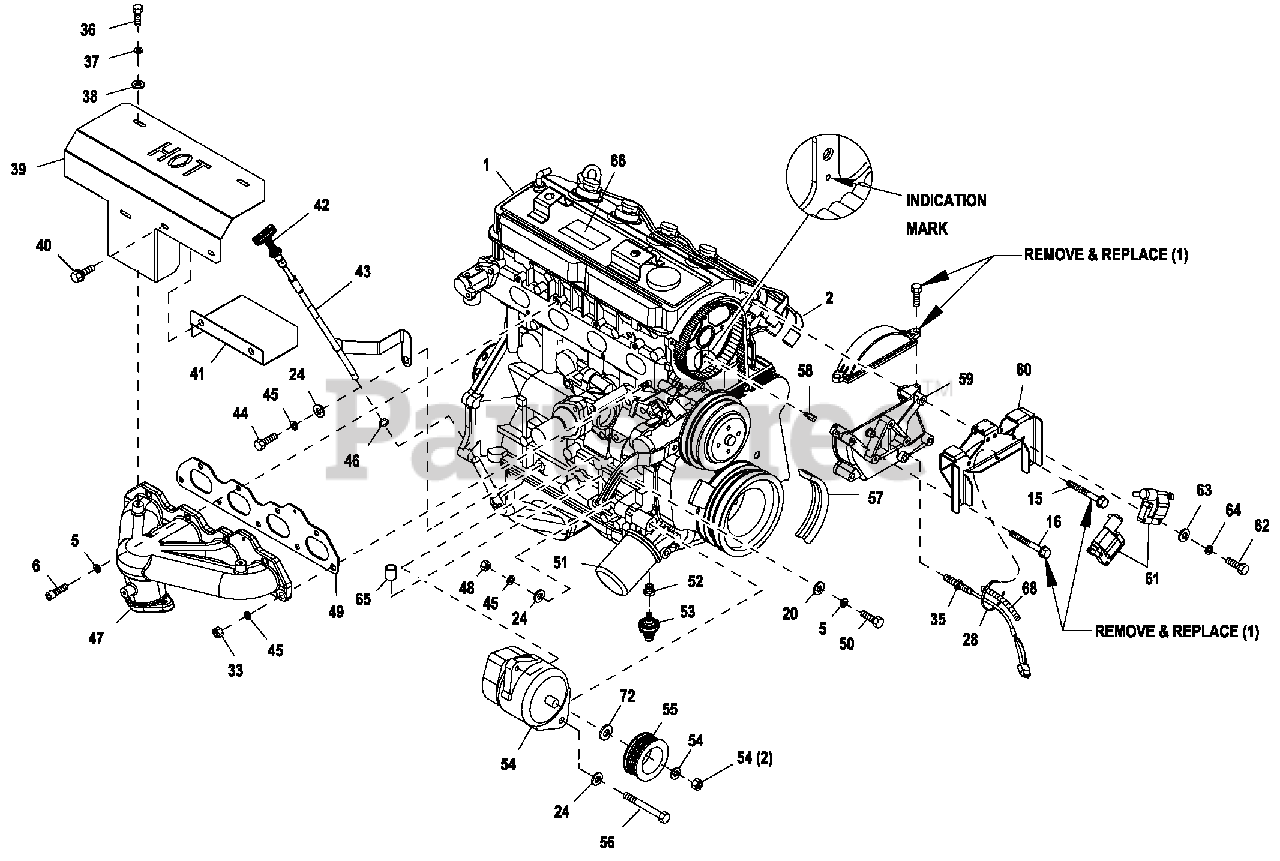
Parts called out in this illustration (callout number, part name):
1	ENGINE 2.4L G2
2	SPARK PLUG WIRE SET 2.4L G2 IG
5	WASHER LO CK M8-5/16
6	SCREW SHC M8-1.25 X 25 C12.9
15	SCREW HHC M8-1.25 X 70 C8.8
16	SCREW HHC M8-1.25 X 65 C8.8
20	WASHER FLAT 5/16-M8 ZINC
24	WASHER FLAT 3/8-M10 ZINC
28	TIE WRAP U L 7.4"X .19" B LK
33	NUT HEX M10-1.25 G8 YEL CHR
35	ASSY MAGPICKUP (3/8-24 MALE)
36	S CREW HHC M6-1.0X1 2 G8.8
37	WASHER LO CKM6-1/4
38	WASHER FLAT 1/4-M6 ZINC
39	SHIELD EXHAUST
40	SCREW HHTT M6-1.0 X 16 ZY C
41	SHIELD HEAT SML
42	ASSEMBLY DIPSTICK G2.4L
43	ASSY DIPSTICK TUBE 2.4 G2
44	S CREW HHC M10-1.25 X 20 C8.8
45	WASHER LO CKM10
46	O-RING SIZE 9.0MM X 2.0MM NITR
47	EXHAUST MANIFOLD G2 (MACHINE)
48	NUT HEX M10-1.5 G8 YEL CHR
49	GASKET EXHAUST MANIFOLD
50	S CREW HHC M8-1.25 X 25 C10.9
51	FILTER 1.5L/2.4L G2 OIL
52	ADAPTOR 1/8 NPTF TO 1/8 BSPT
53	SWITCH OIL PRESSURE 10 PSI 2 POL
54	ALTERNATOR D C W/OUT PULLEY
55	PULLEY D C ALTERNATOR
56	S CREW HHC M10-1.5 X 120 C8.8
57	BELT SERPENTINE 37.0"
58	CAM SENSOR PIN ASSY
59	C OVER CAM GEAR G2 REWORKED
60	BRA CKET ASM-2.4L C OIL G2
61	C OIL-2.4L G2 IGNITION
62	S CREW HHM #10-32X1-1/4
63	WASHER FLAT #10 ZINC
64	WASHER LOCK #10
65	PLUG TAPER
66	DECAL SORE EPA CERTIFICATIO
67	ADAPTER DRAIN OIL
68	CO N DUIT FLEX .25"ID (6"LG)
72	SPACER DC ALTER NATOR PULLEY
